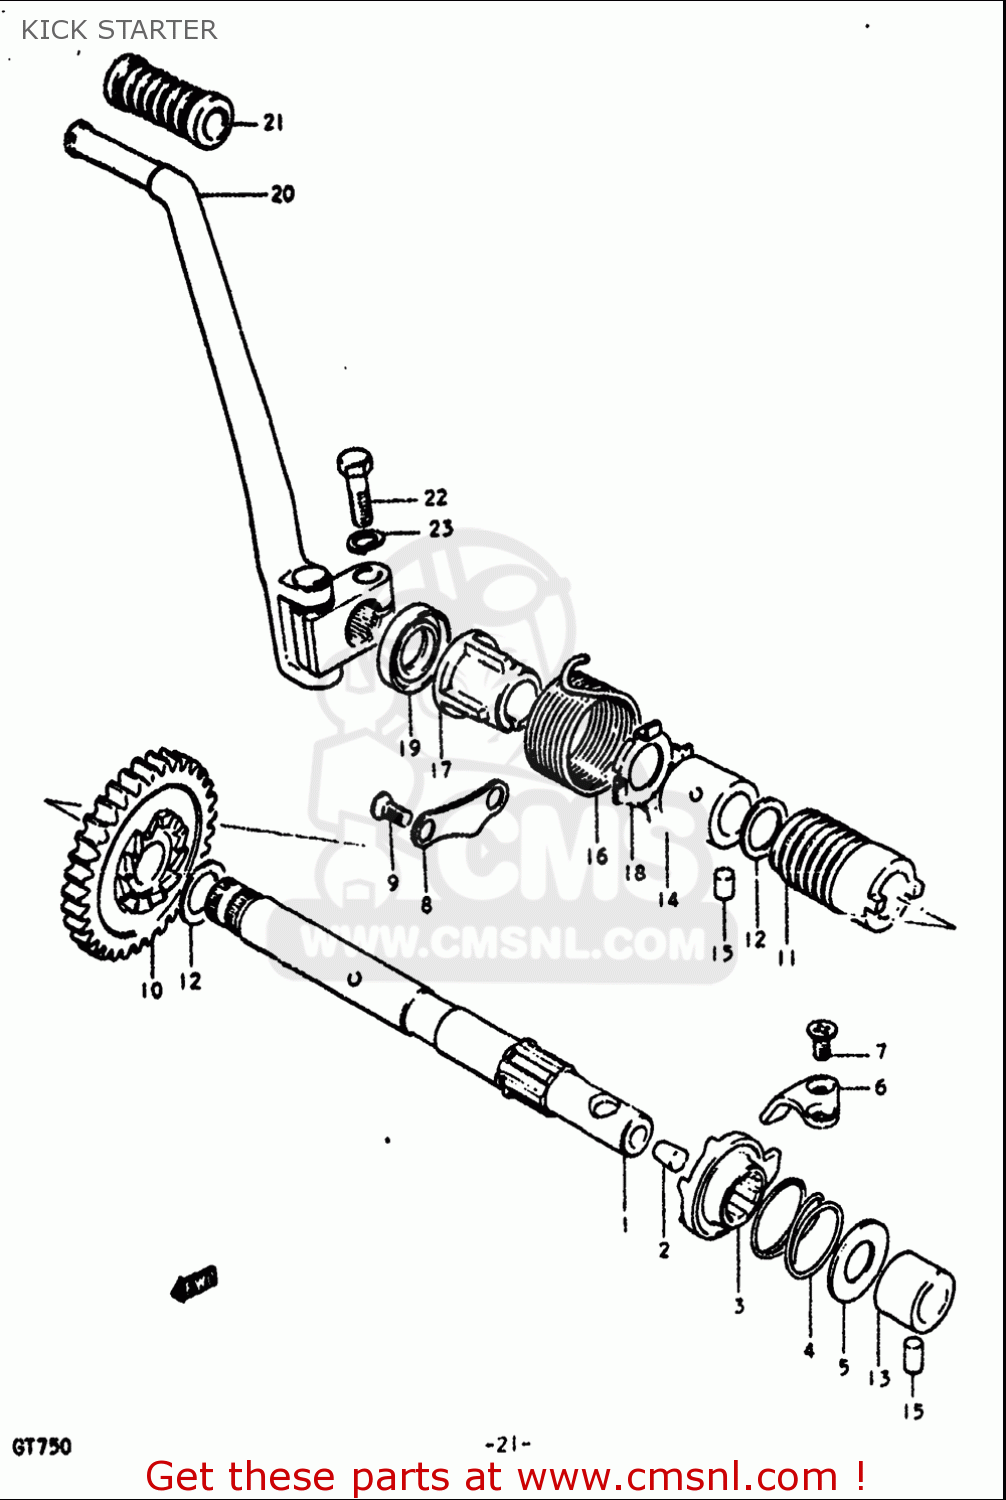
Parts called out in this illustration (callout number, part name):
2	PLUG
3	STARTER,KICK
4	SPRING
5	WASHER
6	GUIDE,KICK STARTER
7	SCREW
9	SCREW
12	SHIM(20X28X1)
15	PIN
16	SPRING
18	HOLDER,KICK SHAFT SPRING
19	SEAL,OIL(20X37X7)
21	RUBBER,KICK STARTER PEDAL
22	BOLT
23	WASHER,LOCK
